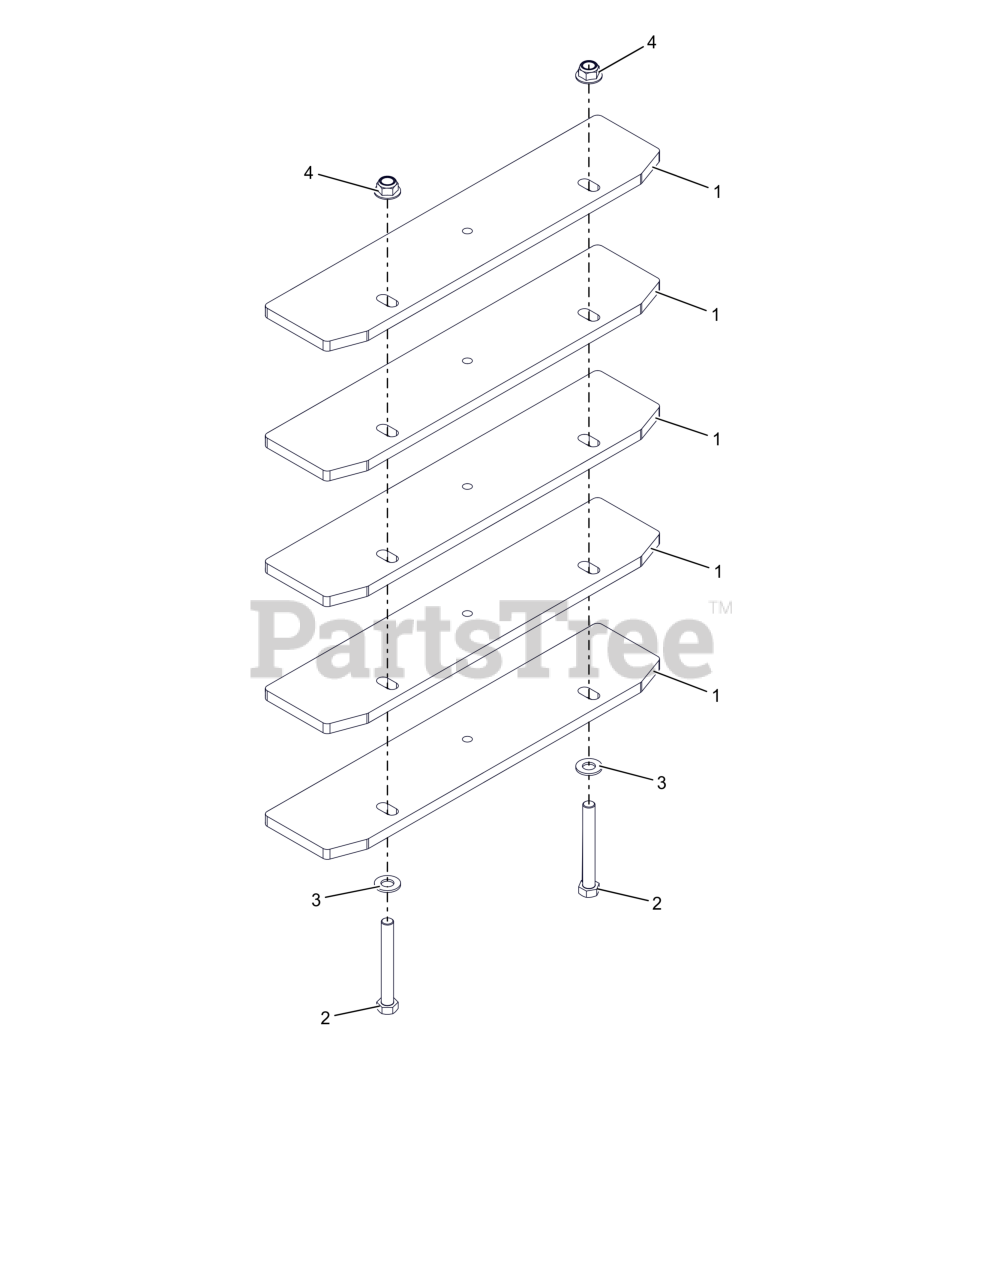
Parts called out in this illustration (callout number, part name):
1	PLATE, COUNTER WEIGHT
2	BLT, HEX .50-13X4.00 G5 ZCC
3	WSHR,FLT .531X1.062X.095 ZCC
4	NUT,NYL-FLG .50-13 GF ZCC
